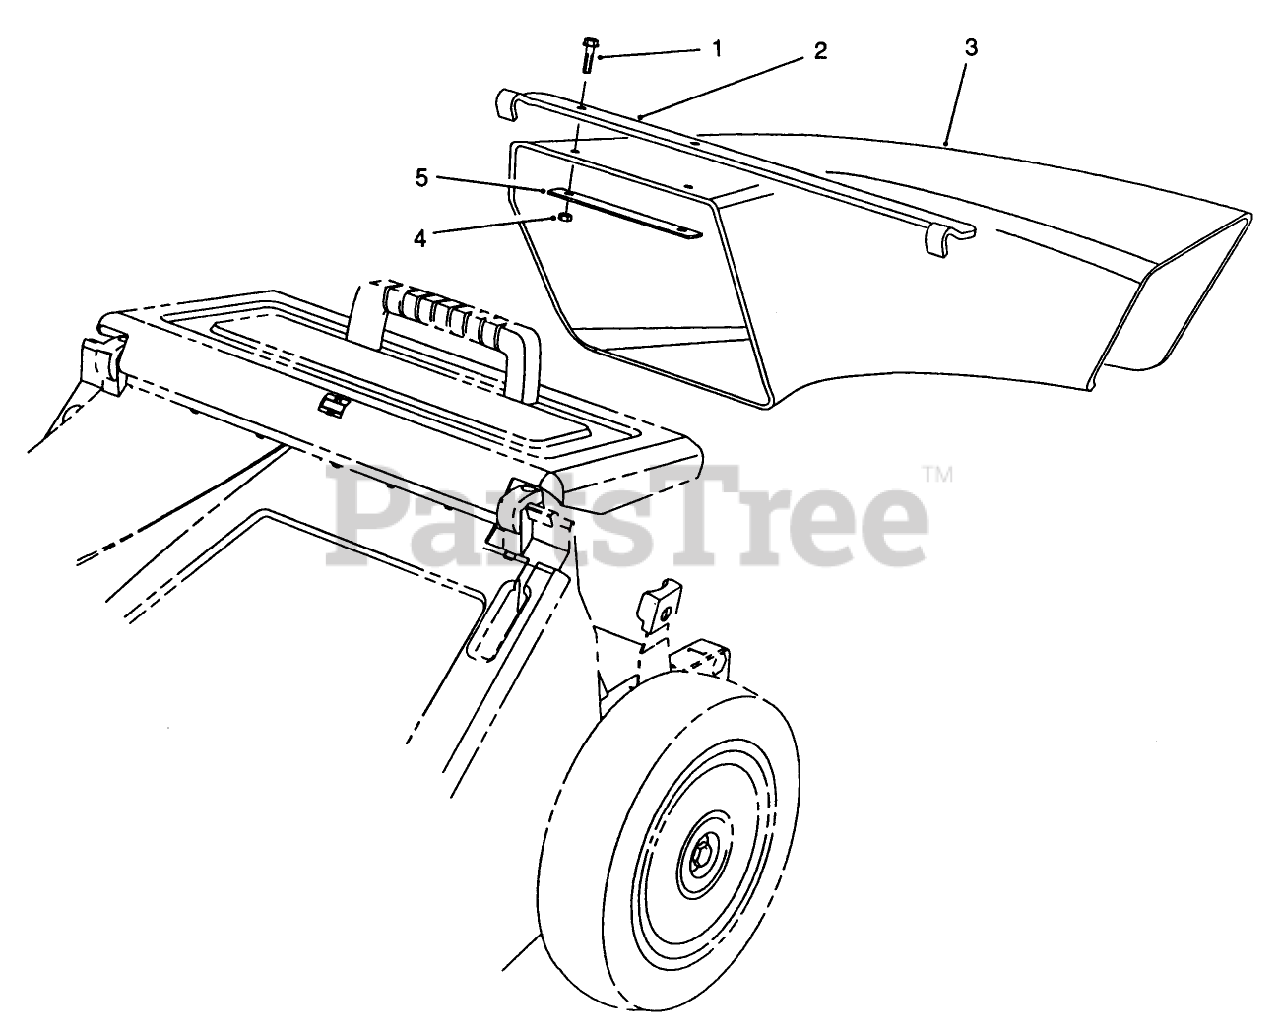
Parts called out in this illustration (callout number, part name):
1	SCREW-HWH
2	CHUTE HANGER BRACKET*
4	NUT-LOCK, NI
